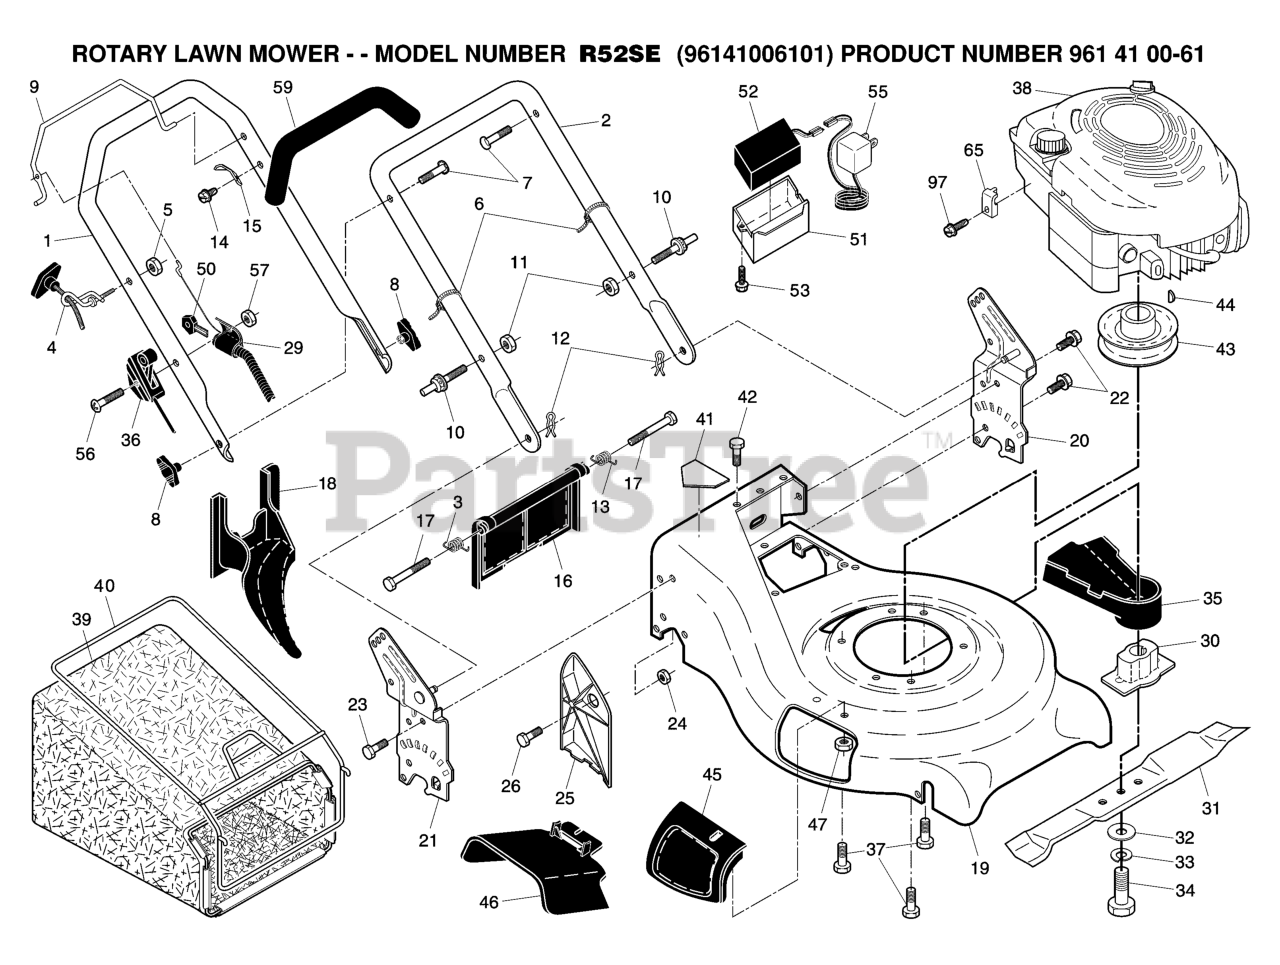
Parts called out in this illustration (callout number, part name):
1	UPPER HANDLE
2	HANDLE.LOWER.21.GREY
3	SPRING.LH.REAR.DOOR.21.RWGD
4	RB GUIDE.ROPE.STD.BLK.ZIN WSL
5	NUT
6	TIE GUIDE
7	BOLT, HANDLE 5/16-18X1.75
11	NUT.CENTERLOCK.5/16-
12	HAIRPIN COTTER
13	SPRING.RH.REAR.DOOR.21.RWGD
15	BRACKET UPSTOP
16	DOOR.REAR.PLASTIC.21.RWGD.BLAC
18	PLUG.MULCHER.RGD.21.
20	BRKT.ASM.HNDL.21.RWGD.LT
21	BRKT.ASM.HNDL
22	SELF-TAPPING SCREW 5/16-18X3/4
23	BOLT, HEX HEAD 5/16-18
24	NUT.71038.31-18.HEX.NYLOCK
25	CLIPPING DEFLECTOR
29	CONTROL.COMBI.KEY.ASMR
30	ADAPTER.BLADE
31	BLADE.21.PUSH
32	WASHER,HARDEN
33	LOCKWASHER
34	SCREW, HEX HD 3/8-24 X 1-3/8
36	CONTRL.THROTTLE.
37	BOLT 3/8-16X1-1/8
40	FRAME.CATCHER.21.RGD.AG
41	DECAL.INTERNATIONL.CUTFINGER
43	PULLEY.ENG.25MMM
44	HI-PRO KEY
45	MULCHER DOOR ASM.
46	DEFLECTOR, DISCHARGE
50	KEY.MOLDED
51	BOX.BATTERY.21RD.,RWGD
52	BATTERY WITH AMP CONECTOR AGM
53	SCREW.HWH.13-16X1.12
55	CHARGER.BATTERY.CE
56	SCREW 1/4-20 X 2.12
59	GRIP.HANDLE.FOAM
65	CABLE CLAMP(ENGINE)
97	SCREW.HEX.HEAD.WASHER.10-16
